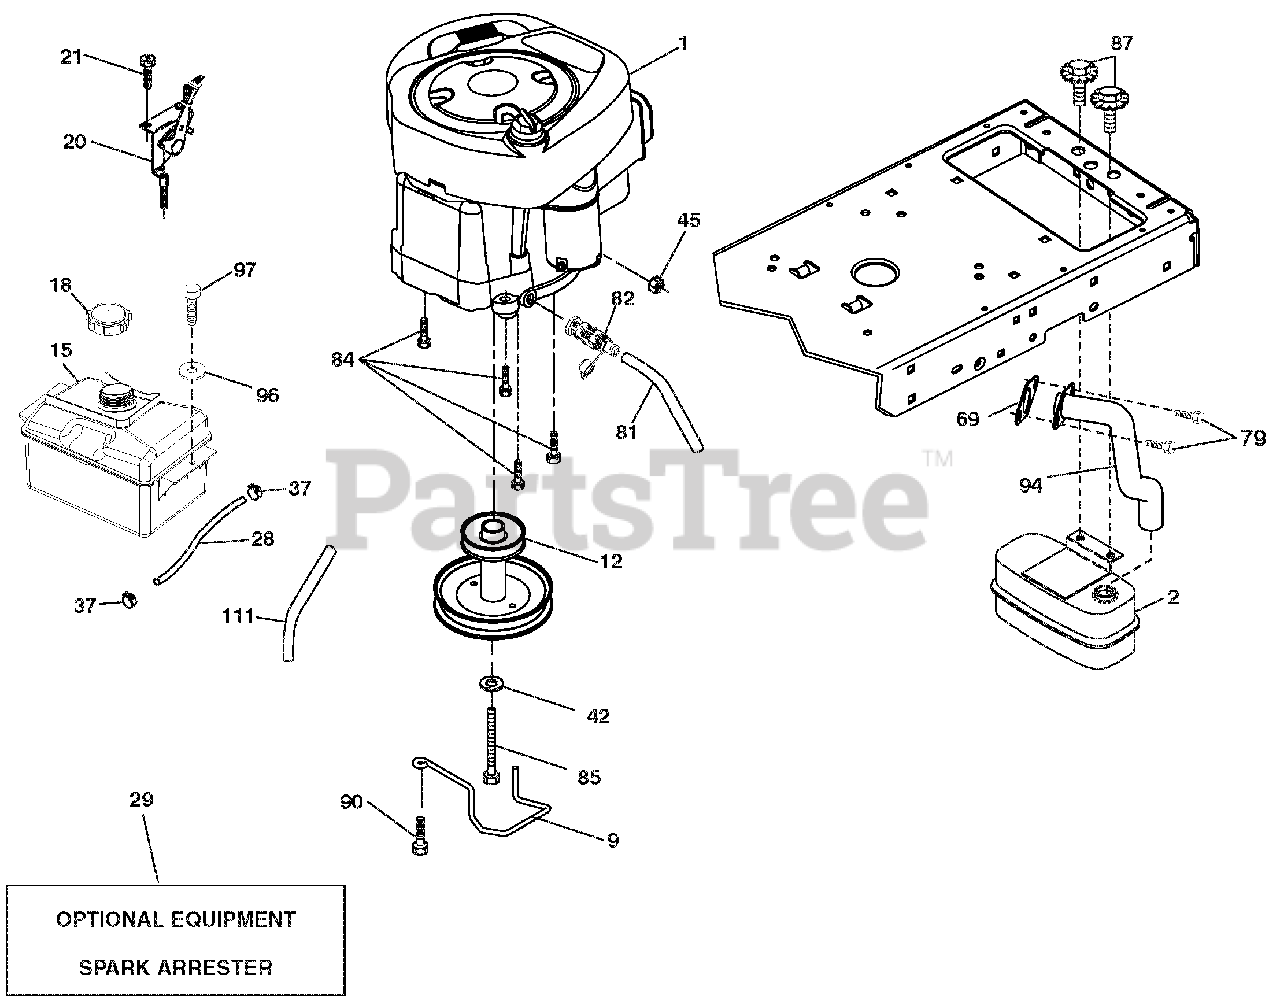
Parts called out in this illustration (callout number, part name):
1	0009-G1(586070701)(ORDER PARTS
1	FROM ENGINE MANUFACTURER.)
2	MUFFLER
9	KEEPER BELT ENGINE
12	ENGINE PULLEY
15	TANK FUEL
18	CAP.FUEL
20	CONTROL THROTTLE/CHOKE
28	LINE.FUEL.22"FRONT.EMIS.CA.LP
29	KIT.SPARK ARRESTOR(392390 B&S)
37	CLAMP.HOSE.BLK.
42	WASHER.LOCK.HVY HLCL.SPR.7/16
45	Nut, Keps Hex 1/4-20 unc
69	Gasket Eng 1 313 Id Tin Plated
79	SCREW.SOCKET HD.5/16-18 X .75
81	TUBE.DRAIN.OIL.EASY
82	VALVE OIL DRAIN
84	Screw 3/8-16 x <
85	BOLT.HEX.7/16-20X4XGR5-1.5THR.
87	BOLT.5/16-18UNCX3/4 W/SEMS.BLK
90	SCREW.3/8-16X1.SMGML.TAP/R.BLK
94	EXHAUST TUBE
96	WASHER.9/32 X 7/8 X 16GA.
97	SCREW.HEXWSH.THDROL.1/4-20X3/4
111	PURGE.LINE.CARB
